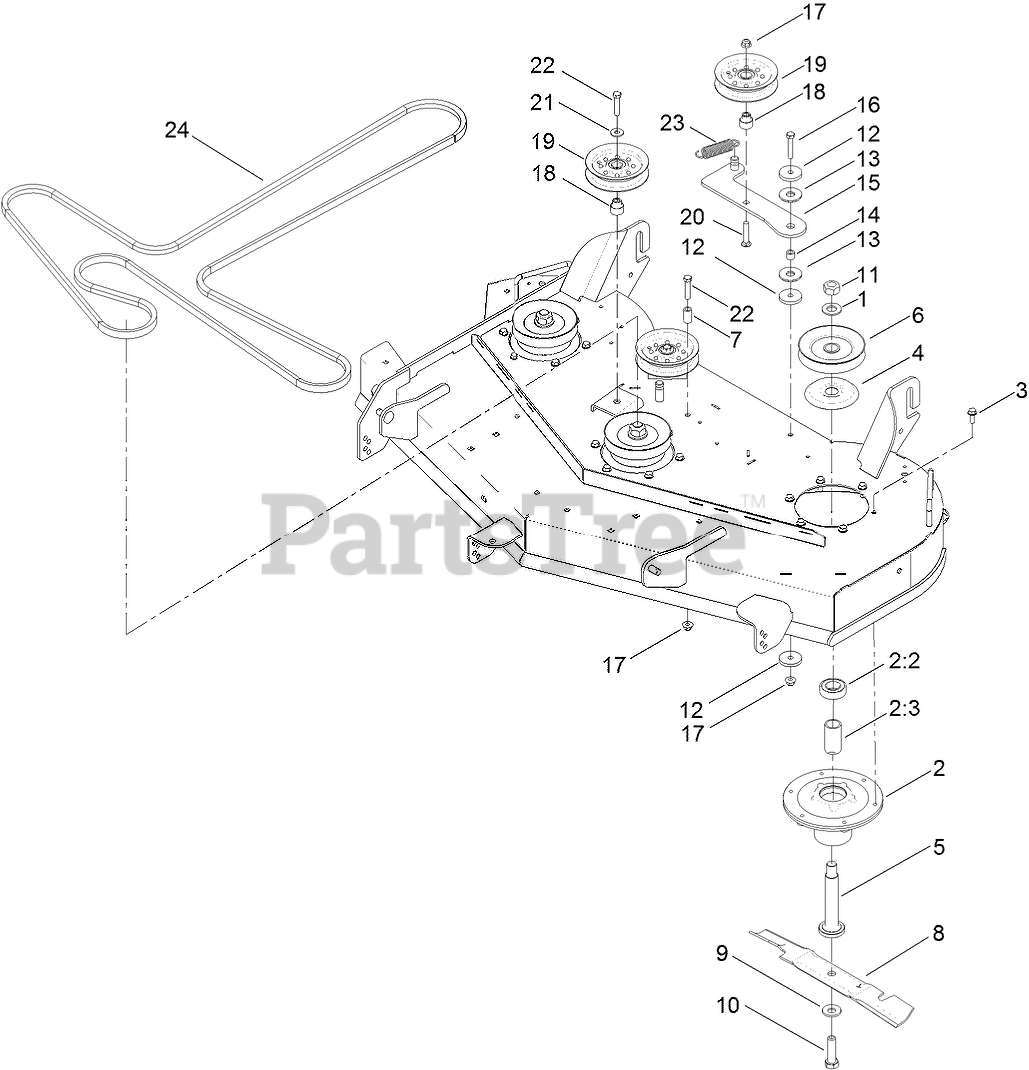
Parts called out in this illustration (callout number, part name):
1	WASHER
2	SPINDLE ASM
2:2	BEARING-BALL
2:3	SPACER-BEARING
3	SCREW-TAPTITE
4	SHIELD-BEARING
5	SHAFT-SPINDLE
6	PULLEY
7	SPACER
8	BLADE-HI FLO, 16.50 INCH
9	WASHER-BELLEVILLE
10	SCREW-BLADE
11	NUT-HEX
12	WASHER-PLAIN
13	WASHER-FRICTION, COMPOSITE
14	BUSHING-LEVER, LIFT
15	ARM-IDLER
16	SCREW-HH
17	NUT-HF, NI
18	BUSHING-IDLER
19	PULLEY-IDLER
20	SCREW-CARR
21	WASHER-HARDENED
22	SCREW-HH
23	SPRING-EXTENSION
24	V-BELT
